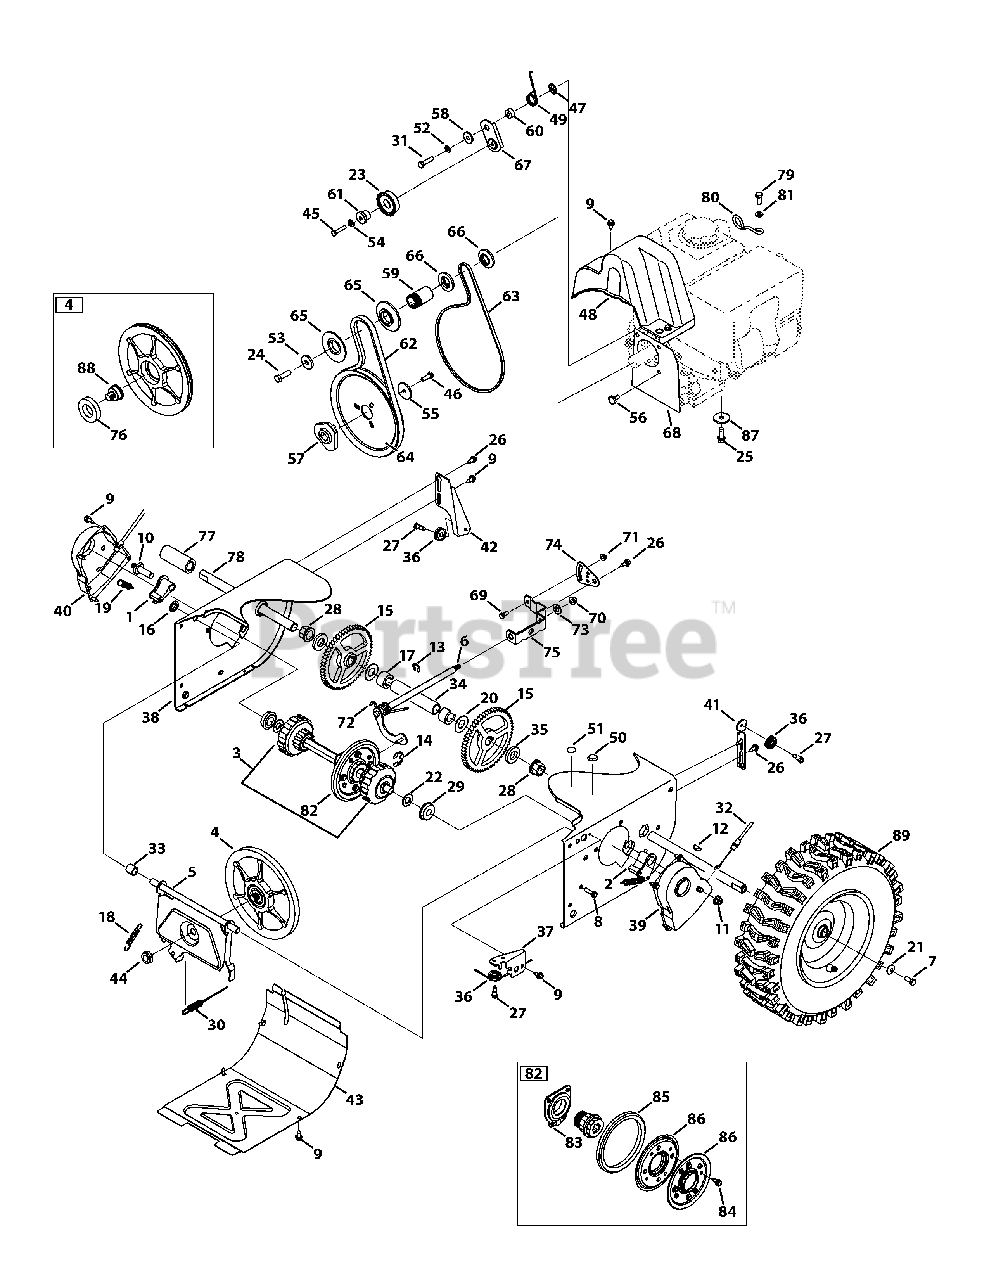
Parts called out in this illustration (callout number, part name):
1	Dogg Assembly, RH
2	Dogg Assembly, LH
3	Drive Shaft Assembly
4	Friction Wheel Disc Assembly
6	Rod Shift Assembly
7	Hex Head Screw, 5/16-24 x .750
8	Screw, 1/4-20 x 1.000
9	Screw, 1/4-20 x .625
10	Actuator Shaft
11	Nut, Flangelock, 3/8-16
12	Hi-Pro Key, 3/16 x 3/4 DIA
13	E-Ring
14	Retainer Ring
15	Gear, 56T
16	Nut, Speed, .500
17	Spacer, .76 x .75
18	Extension Spring, .380 x 2.500
19	Extension Spring, .500 x 1.71
20	Washer, Flat, .76 x 1.49
21	Washer, Bell, .340 x .872
22	Washer, Flat, .58 x 1.125
23	Pulley Assembly
24	Hex Head Screw, 3/8-24 x 1.25
25	Taptite Sems Screw, 3/8-16 x 1.000
26	Screw, Shoulder, .368 x .113 x 1/4-20
27	C Screw, Shoulder, .340 x .335 x 1/4-28
28	Hex Flange Bearing, .75 ID
29	Ball Bearing, .5625 x 1.375 x .4375
30	Drive Clutch Cable
31	Hex Head Screw, 5/16-24 x 1.25
32	Steering Cable
33	Spacer, .508 x .75
34	Axle Support Tube
35	Spacer, Axle
36	Roller Cable
37	Auger Cable Guide Bracket
38	Wheel Drive Frame - Orange
38	Wheel Drive Frame - Black
39	Shaft Retainer, LH
40	Shaft Retainer, RH
41	Auger Clutch Cable Guide Bracket
42	Drive Clutch Cable Guide Bracket
43	Frame Cover - Orange
43	Frame Cover - Black
44	Nut, Flange, 5/8-18
45	Taptite Screw, 1/4-20 x 1.250
46	Hex Head Screw, 5/16-24 x .875
47	Nut, Push-On, .25 DIA
48	Belt Cover
48	Belt Cover (208cc engine)
49	Spring, Torsion, .850 x .333
50	Plug, 3/8 ID
51	Plug, 1/2 ID
52	Washer, Lock, 5/16
53	Washer, Flat, .406 x 1.25
54	Washer, Lock, 1/4
55	Washer, Flat, .34 x 1.50
56	Screw, Shoulder
57	Pulley Adapter, .75 DIA
58	Spacer, Shoulder, .3175 x .500
59	Spacer, .875 x 1.185
60	Spacer, .340 x .750
61	Spacer, Shoulder, .260 x .785
62	Belt, .500 x 37.00
62	Belt, .500 x 35.06
63	V Belt, 3/8 x 35.68"
63	V-Belt, 3L x 34.13
64	Auger Pulley, 8.1 x .5
65	Pulley, Half, 4L-V x 2.600
66	Pulley, Half, 3/8-V x 1.7160
67	Drive Idler Bracket
68	Cover Plate
68	Cover Plate (208cc engine)
69	Hex Head Screw, 1/4-20 x .620
70	Nut, Flangelock, 5/16-18
71	Nut, Flangelock, 1/4-20
72	Spring, Torsion, .750 x .968
73	Washer, Flat, .469 x .875 x .105
74	Speed Selector Pivot Bracket
75	Speed Selector Shift Bracket
76	Ball Bearing, 30 x 55 x 13
77	Spacer, 1.25 x .75 x 3.00
78	Axle, .75 x 11.12
79	Hex Head Screw, 1.25 x 20
80	Cable Guide
80	Cable Guide (208cc engine)
81	Washer, Flat, .330 x .630
82	Friction Wheel Assembly
83	Bearing Assembly, Friction Wheel
84	Screw, 1/4-14 x .625
85	Friction Wheel, 5.5 OD
86	Friction Wheel Plate
87	Washer, Flat, .38 x 1.38
88	Friction Pin, Disc Bearing
89	Wheel, LH, 16 x 6.5-8
89	Wheel, RH, 16 x 6.5-8
